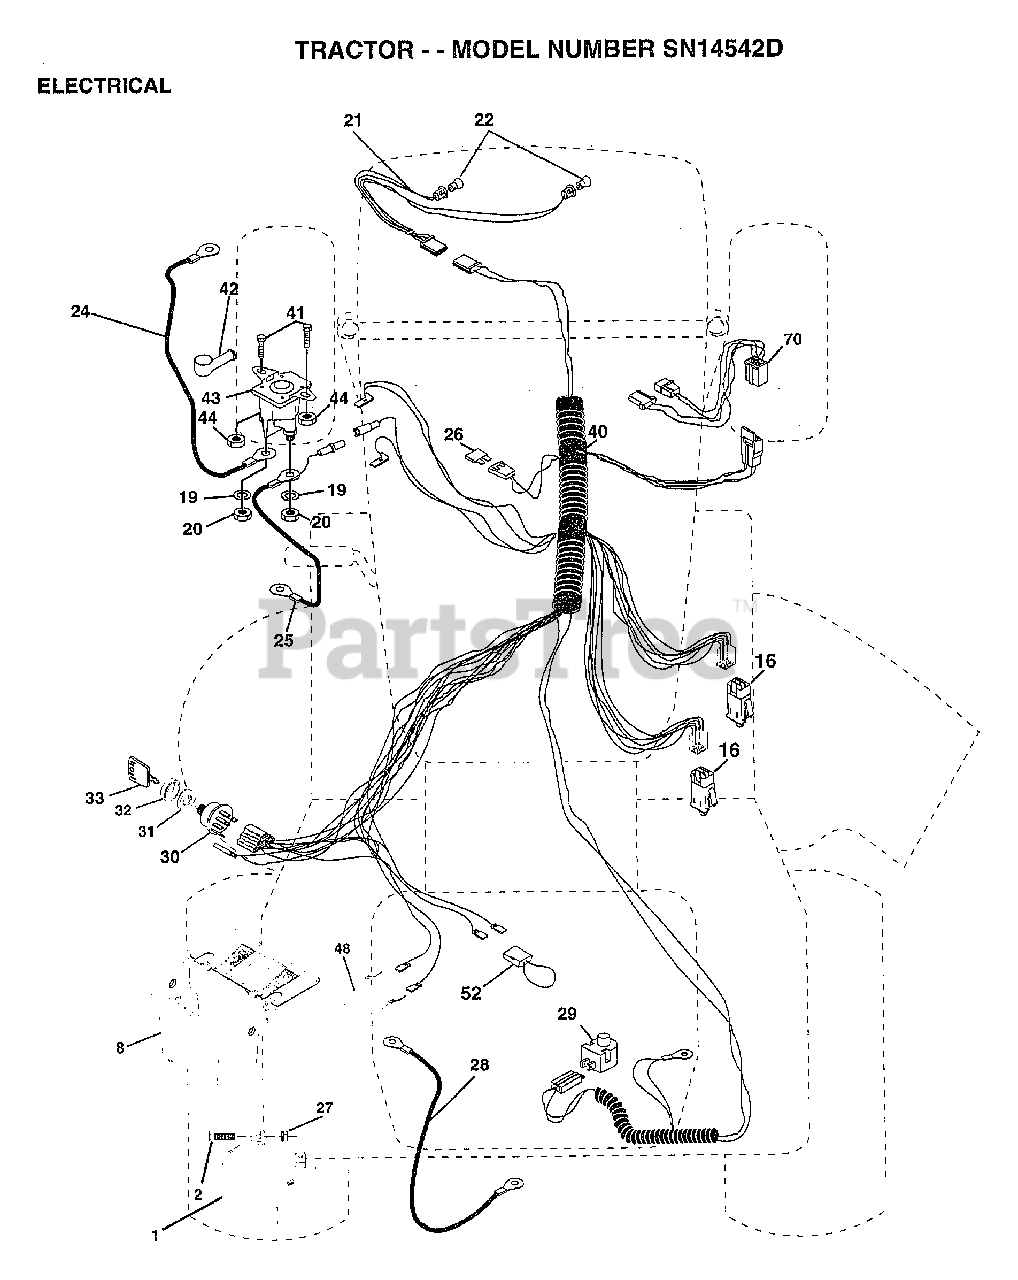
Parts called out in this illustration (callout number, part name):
2	BOLT LT
8	"CASE,BATTERY.MECH"
16	SWITCH INTERLOCK
20	NUT
21	HARNESS.ASM.LIGHT W/4152J
22	HEADLAMP BULB
24	"CABLE T, BATTERY"
25	CABLE.BTRY.6GA.RD
26	FUSE.15 AMP
27	NUT
28	CABLE GROUND
29	SWITCH SEAT
30	SWITCH IGN 4POS
31	NUT IGNITION
32	COVER KEY SWITCH
33	KEY
40	HARNESS.IGNITION
41	BOLT HXHD FIN
44	NUT HXKEP 1/4X20
48	ADAPTER AMMETER
52	PROTECTION LOOP
70	HARNESS.ENGINE.B&S
